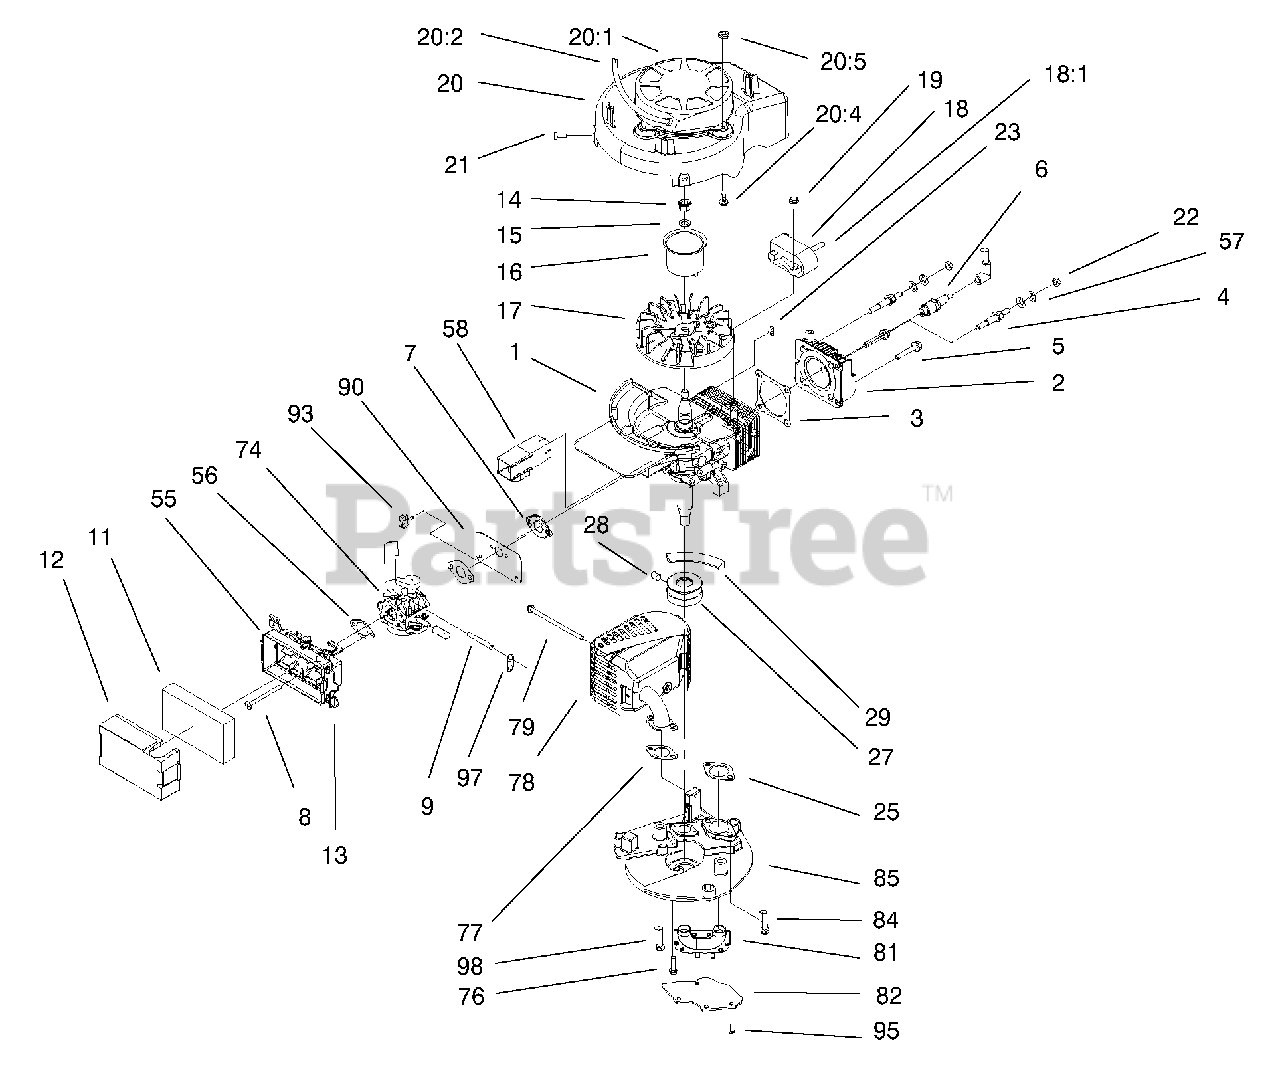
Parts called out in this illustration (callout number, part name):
1	ASM-Short Block
2	Head-Cylinder
3	Gasket-Head
5	Bolt-Head
6	Plug-Spark
7	Gasket-Intake
9	Hose-Primer
11	Filter-Air
12	Cover-Air Filter
13	Retainer-Filter Cover
15	Washer-Lock
16	Cup-Starter
17	Flywheel
18	Module-Ignition
18:1	Clip-High Tension Lead
20	Shroud-Recoil
20:1	Recoil And Decal ASM
20:4	Screw-HWH
20:5	Nut-Lock
21	Screw-HH
25	Gasket-Exhaust
28	Screw-Set,Cone Point
42	Lead-Wire
55	Air Base ASM
56	Gasket-Filter
57	Washer-Belleville
58	Tunnel-Inlet
74	Carburetor ASM With Gaskets
78	Muffler And Guard ASM
79	Bolt-Console
81	Pipe-Transfer
82	Cover-Muffler
84	Screw-HH
85	Muffler Plate
90	Shield-Carburetor
93	Retainer-Wire
95	Screw-HH
97	Hose-Retainer
